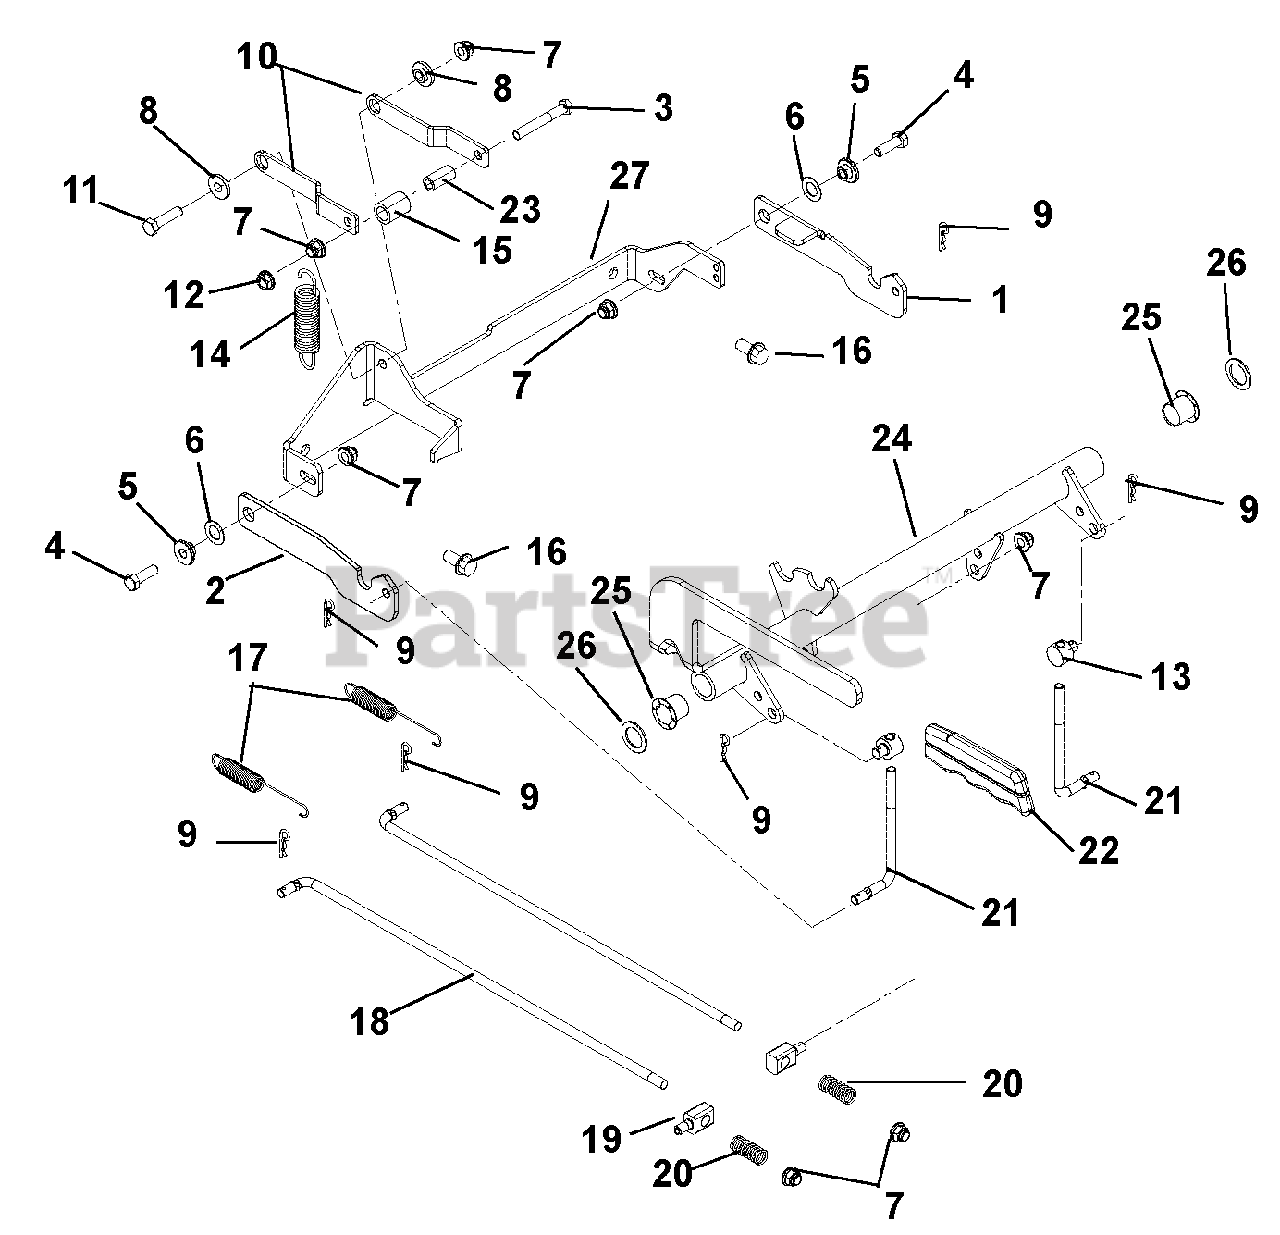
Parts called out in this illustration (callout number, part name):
1	LINK, BRAKE INTERLOCK
2	INTERLOCK, BRAKE
3	BLT-HEX .31-18X2.25 GR5 YWZC
4	BLT-HEX .31-18X1.00 GR5 YWZC
5	BSHG-FLG .32X.500X.344X.880
6	WSHR-FL-STL .505X.875X.024 YWZ
7	NUT-LK-NYL-FLG .31-18 YWZC
8	BSHG, FLG .325X.499X.26X.88
9	PIN-HAIR INT .08X.18X1.18 YWZC
10	ARM, BRAKE CAM
11	BLT-HEX .31-18X1.25 GR5 YWZC
12	NUT-LK-TOP-FLG .31-18 YWZC
13	TRUNNION, BRAKE .31-18 UNC
14	SG-TENS .105X.812X3.88 WLD 15
15	ROLLER, CAM LOCK
16	SCR-TAP .38-16X.75 HWH TR YWZ
17	SG-TENS .056X.60X4.40
18	ROD, PARK BRAKE
19	PIN, PIVOT/TRUNNION
20	SPRING, COMPRESSION
21	LINK, INTERLOCK BRAKE
22	GRIP, PARKING BRAKE (YELLOW)
23	BSHG, SPCR .330X.500X1.01 PM
24	WMT, BRAKE SHAFT
25	BUSHING, IGLIDE CLIP
26	WSHR-FL-STL.754X1.125X.062YWZC
27	BRKT, BRAKE MTG
